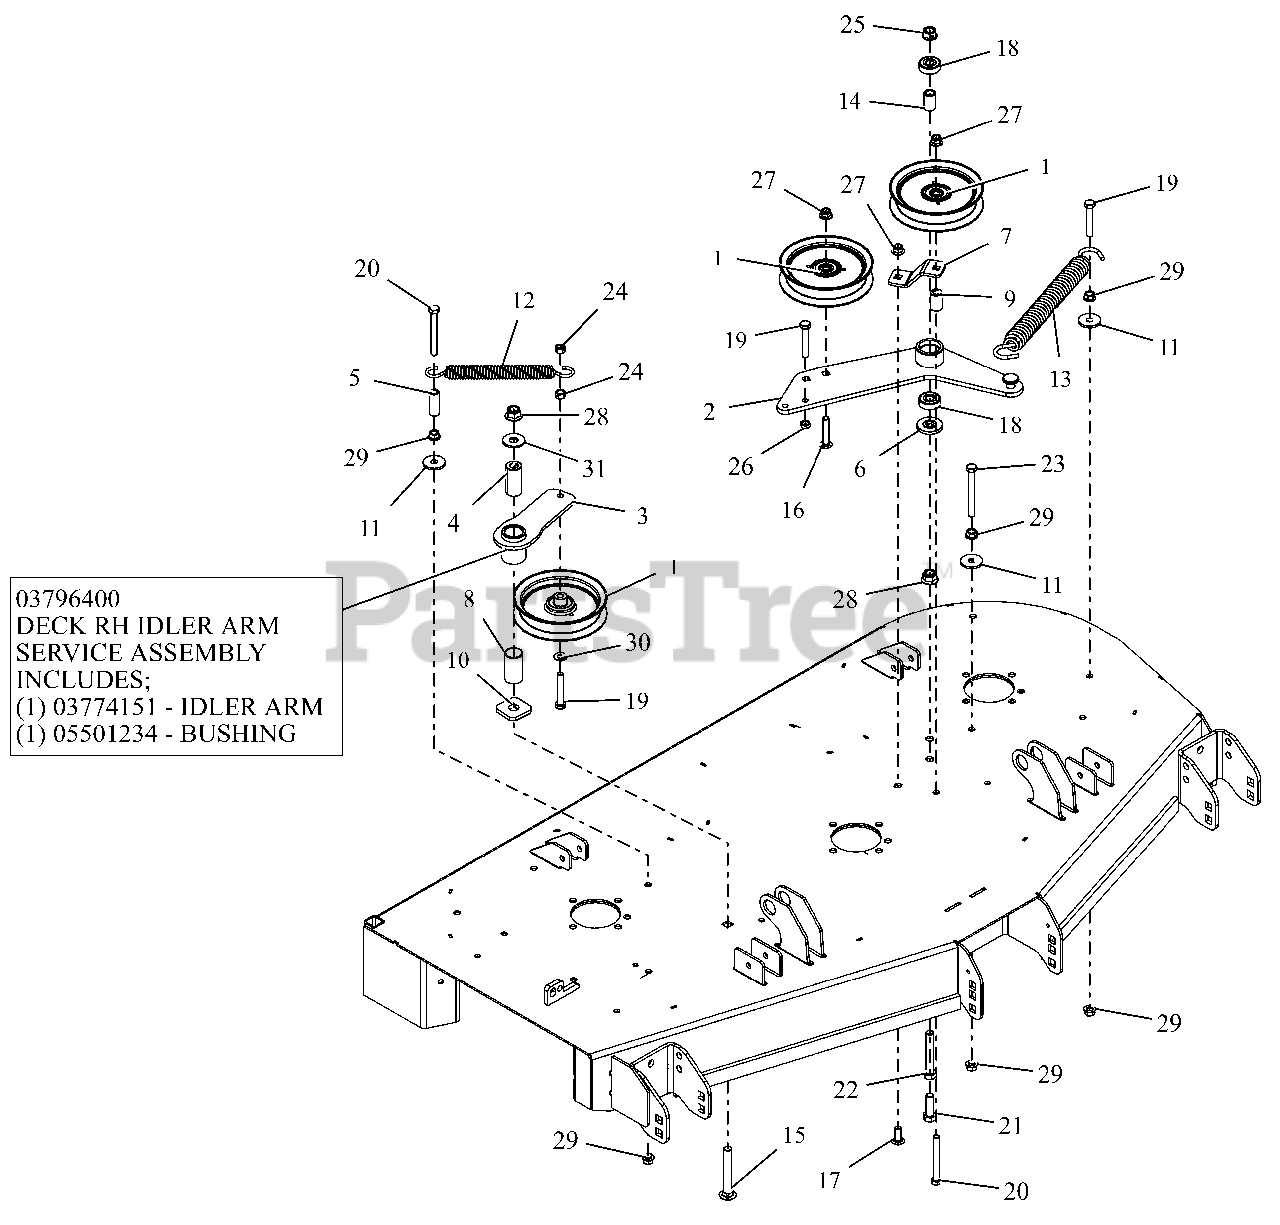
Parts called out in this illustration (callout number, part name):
1	IDLER, FLAT 5.00"
2	DECK PTO IDLER ARM WLDMT - BLK
3	WMT, IDLER ARM - BLACK
3	ASM, IDLER ARM (DECK)
3	BSHG, 1.00X1.125X1.937
4	BSHG, SPCR .502X.997X2.03 PM
5	SPACER, .375IDX.625ODX1.66 PM
6	SPACER, IDLER ARM
7	PTO FIXED IDLER MTG BRKT -RED
8	BSHG, 1.00X1.125X1.937
9	BUSHING, SLV .380X.750X1.190
10	WSHR-FLT .640X1.75X.250
11	WSHR-FL-STL .406X1.375X.135 YZ
12	SPRING, EXTENSION
13	SPRING, EXTENSION
14	SPACER .510 X .75 X 1.1485
15	@BLT-RDHDSQNK .50-13X3.50 G5YZ
16	BLT-RDHDSQNK .38-16X2.00 SHTYW
17	@BLT-RDHDSHSQNK.38-16X1.0 G5YZ
18	BRG-BALL .500X1.38X.437
19	@BLT-HEX .38-16X2.25 GR5 YWZC
20	@BLT-HEX .38-16X3.25 GR5 YWZC
21	@BLT-HEX .50-13X1.50 GR5 YWZC
22	@BLT-HEX .50-13X3.00 GR5 YWZC
23	@BLT-HEX .38-16X3.50 GR5 YWZC
24	@NUT-LK-CTR .38-16 YWZC
25	NUT-LK-CTR-FLG .50-13 YWZC
26	NUT-HEX-JAM .375-16 YWZC
27	@NUT-LK-NYL-FLG .38-16 YWZC
28	@NUT-LK-NYL-FLG .50-13 YWZC
29	@NUT-SPNLK-FLG .375-16 YWZC
30	@WSHR-FL-STL.406X.812X.065 YWZ
31	@WSHR-FL-STL.563X1.38X.109YWZC
